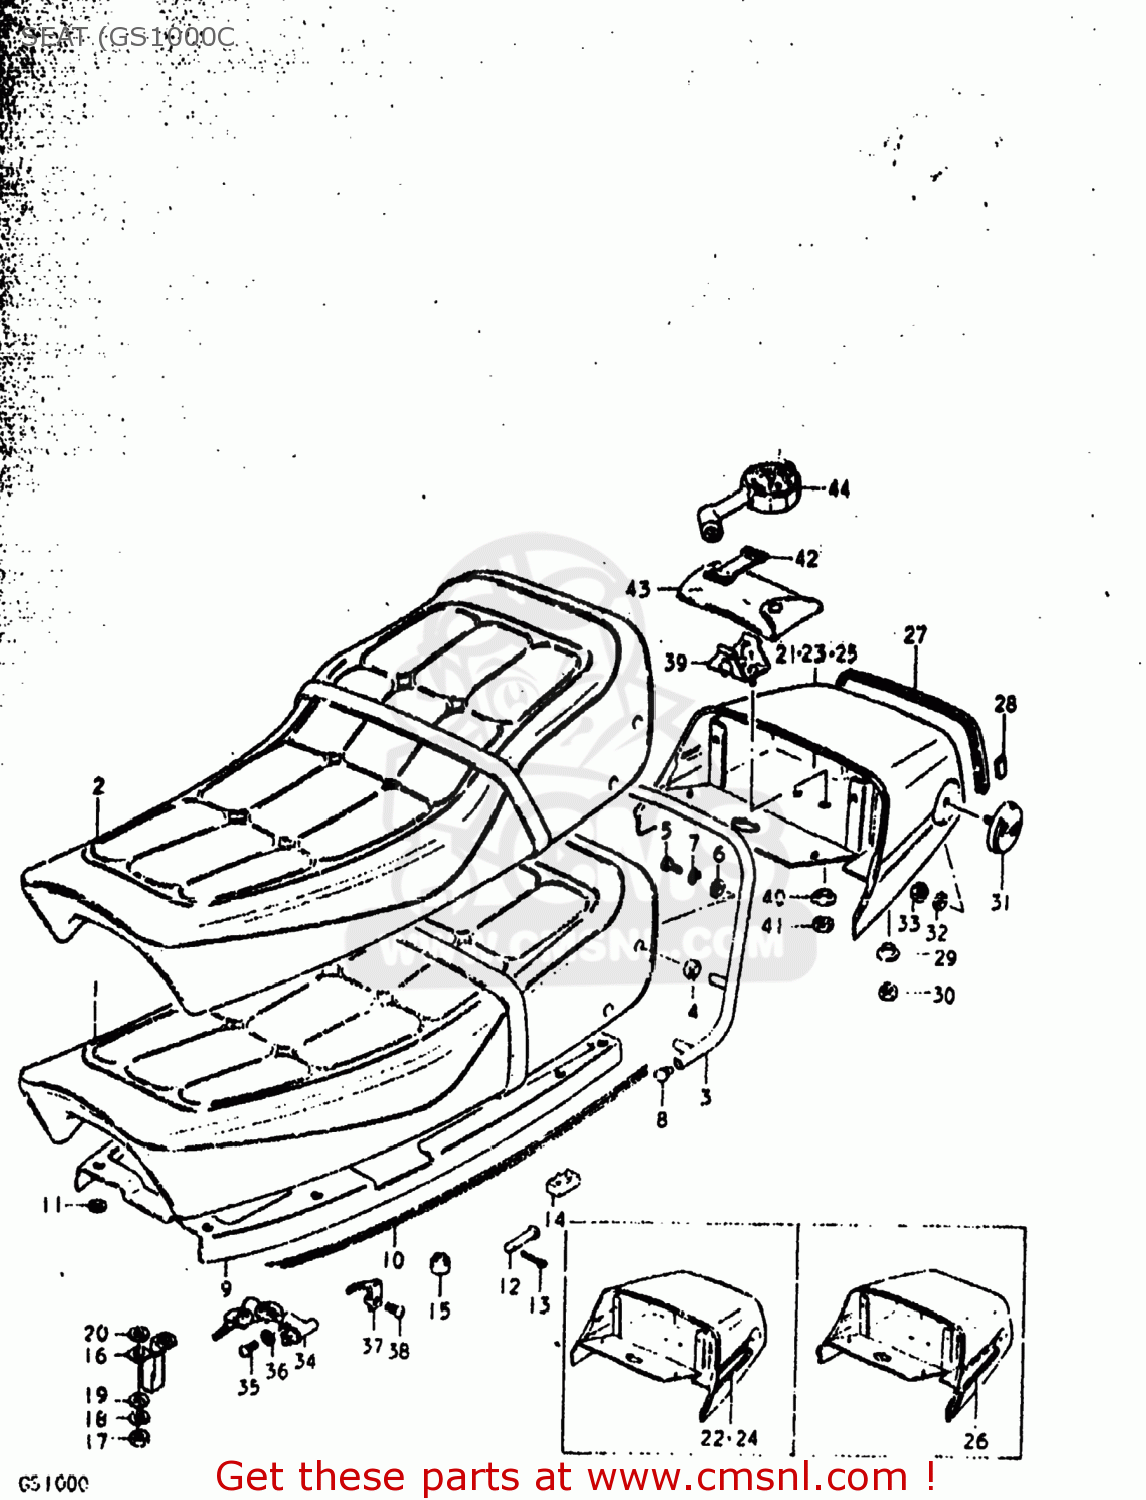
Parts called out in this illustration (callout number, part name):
1	SEAT ASSEMBLY
2	SEAT ASSEMBLY
3	HANDLE,PILLION RIDER
4	CUSHION
5	BOLT
6	WASHER
7	LOCK WASHER
8	END,SHEET HANDLE
9	MOLDING,SEAT
11	NUT
12	PIN
13	PIN
14	CUSHION
15	CUSHION
16	STRIKER,SEAT LOCK
17	NUT
18	LOCK WASHER
19	WASHER
20	WASHER (6.5X20X1.2)
21	COVER,SEAT TAIL
23	COVER,SEAT TAIL
25	COVER,SEAT TAIL
27	GROMMET
28	CLIP,SEAT TAIL COVER M
29	WASHER
30	NUT 6MM
31	REFLEX REFLECTOR,RR
32	WASHER
33	NUT
34	LOCK ASSEMBLY,SEAT
35	SCREW
36	LOCK WASHER
37	SPRING,HELMET HOLDER
38	SCREW
39	HOLDER,TOOL
40	WASHER
41	NUT
42	BAND
43	TOOL SET
44	GAUGE ASSEMBLY,AIR PRESSURE
